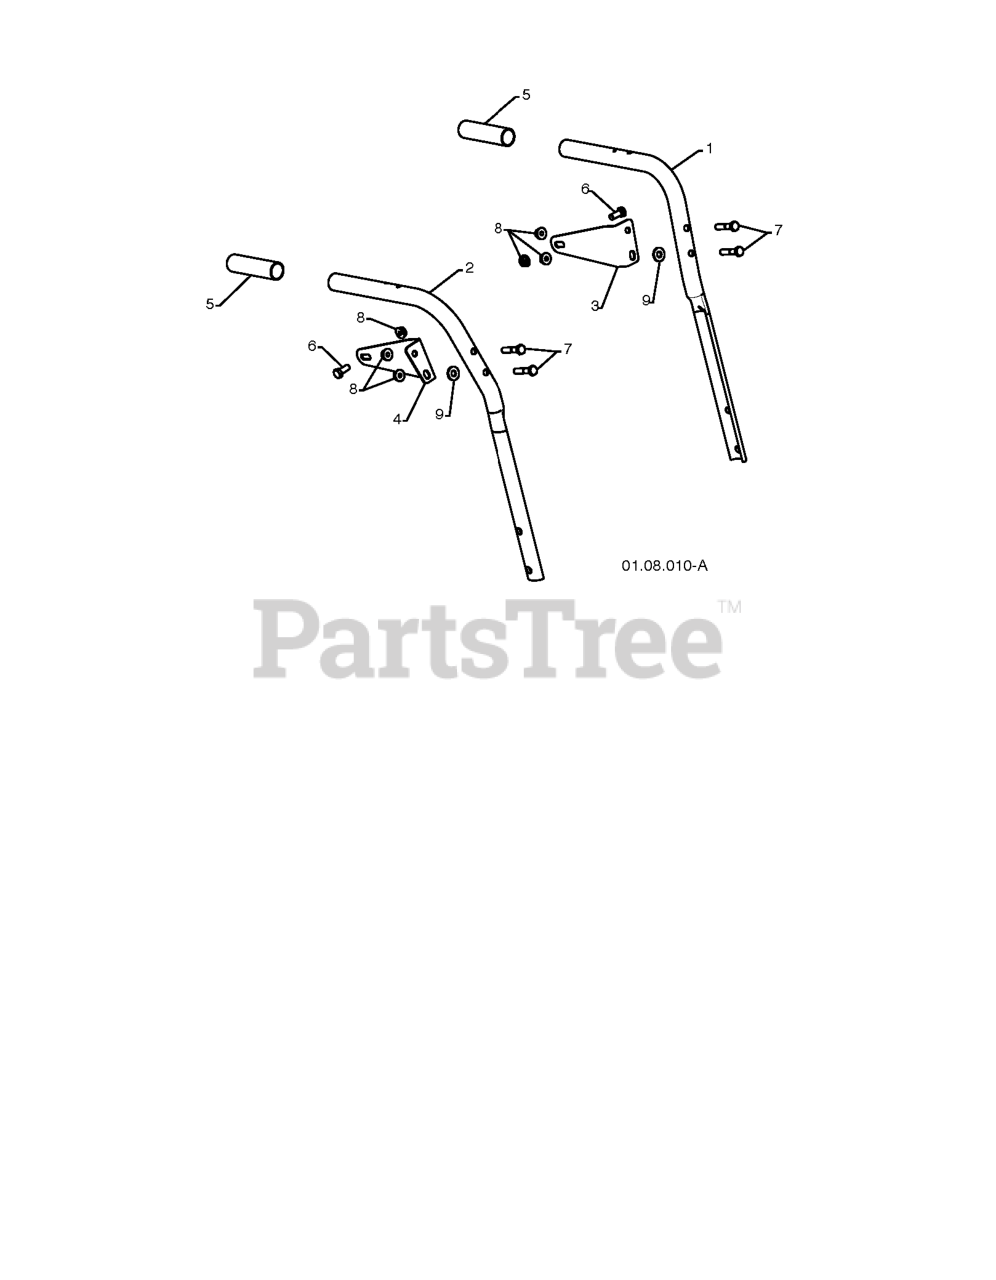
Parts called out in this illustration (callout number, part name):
1	TUBE.HANDLE.PLOW.LH.GREY
2	TUBE.HANDLE.PLOW.RH.GREY
3	BRKT.PANEL.LH.INT
4	BRKT.PANEL.RH.INT
5	GRIP, HANDLE
6	BOLT.FIN.HEX.5/16-18X3/4
7	HEX BOLT
8	NUT.LOCK.5/16-18
9	WASHER.20X8.5
